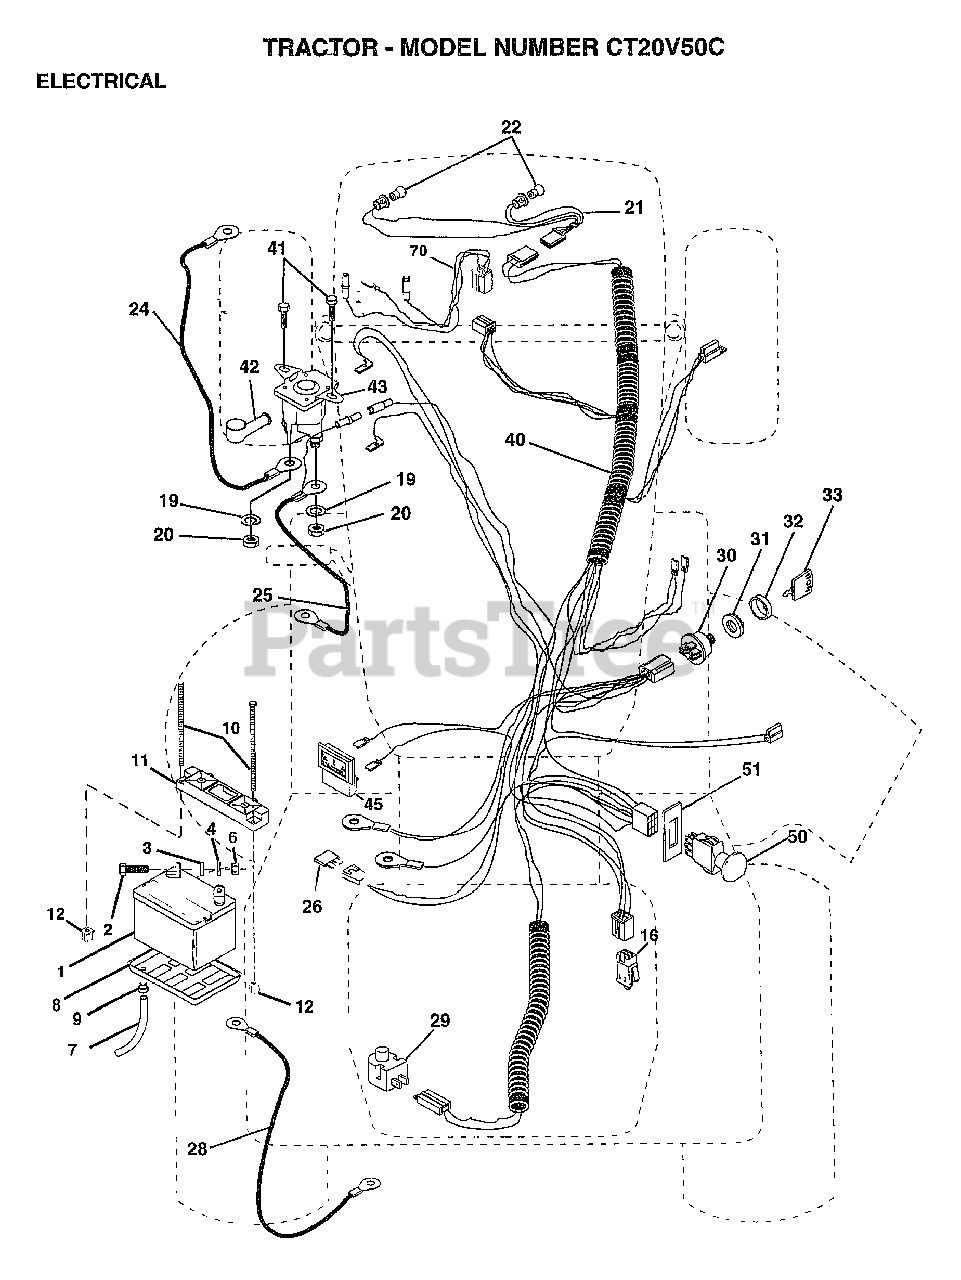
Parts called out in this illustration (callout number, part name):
2	BOLT LT
3	WASHER
4	LOCKWASHER
7	"DRAIN TU T, BATT"
8	"TRAY T, BATTERY"
9	HOSE CLAMP T
11	HOLDDOWN BATTERY
16	SWITCH INTERLOCK
20	NUT
21	"HARNESS,LIGHT SOC"
22	HEADLAMP BULB
24	CABLE-BATTERY T
25	CABLE.6GA.12.5.
26	FUSE HYT
28	CABLE T
29	SWITCH SEAT
30	SWITCH IGN 4POS
31	NUT IGNITION
32	COVER KEY SWITCH
33	KEY
40	"HARNESS,IGNITION"
41	SCREW
45	AMMETER
50	PTO SWITCH.BLK
51	RING RETAIN PTO
70	HARNESS.ENG.VANII
